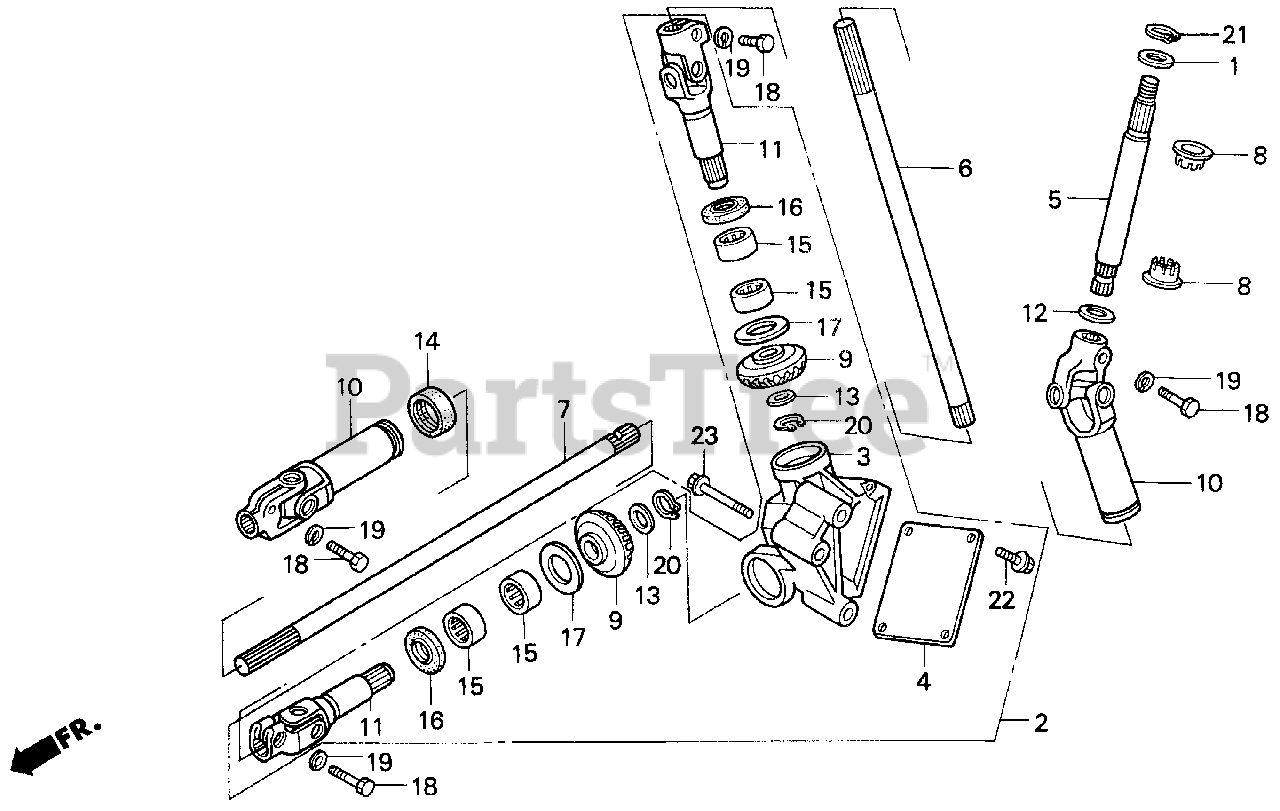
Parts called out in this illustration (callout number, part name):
1	SEAT, FR. RUBBER SPRING
2	GEAR ASSY., STEERING BEVEL
3	CASE, STEERING BEVEL GEAR
4	COVER, BEVEL GEAR CASE
5	SHAFT A, STEERING
6	SHAFT B, STEERING
7	SHAFT C, STEERING
8	BUSH A, STEERING SHAFT
9	GEAR, STEERING BEVEL
10	JOINT ASSY., STEERING
11	JOINT, STEERING BEVEL GEAR
12	WASHER, PLAIN (16MM)
13	WASHER, THRUST (14MM)
14	SEAL, SPLINE (16.5X21X0.75)
15	BEARING, NEEDLE (22X28X12)
16	DUST SEAL (22X35X7)
17	WASHER A, THRUST (26.5X40X2.00)
17	WASHER B, THRUST (26.5X40X2.15)
17	WASHER C, THRUST (26.5X40X2.30)
18	BOLT, HEX. (8X28)
19	WASHER, SPRING (8MM)
20	CIRCLIP (OUTER) (14MM)
21	CIRCLIP (OUTER) (18MM)
22	BOLT, FLANGE (6X16)
23	BOLT, FLANGE (8X50)
